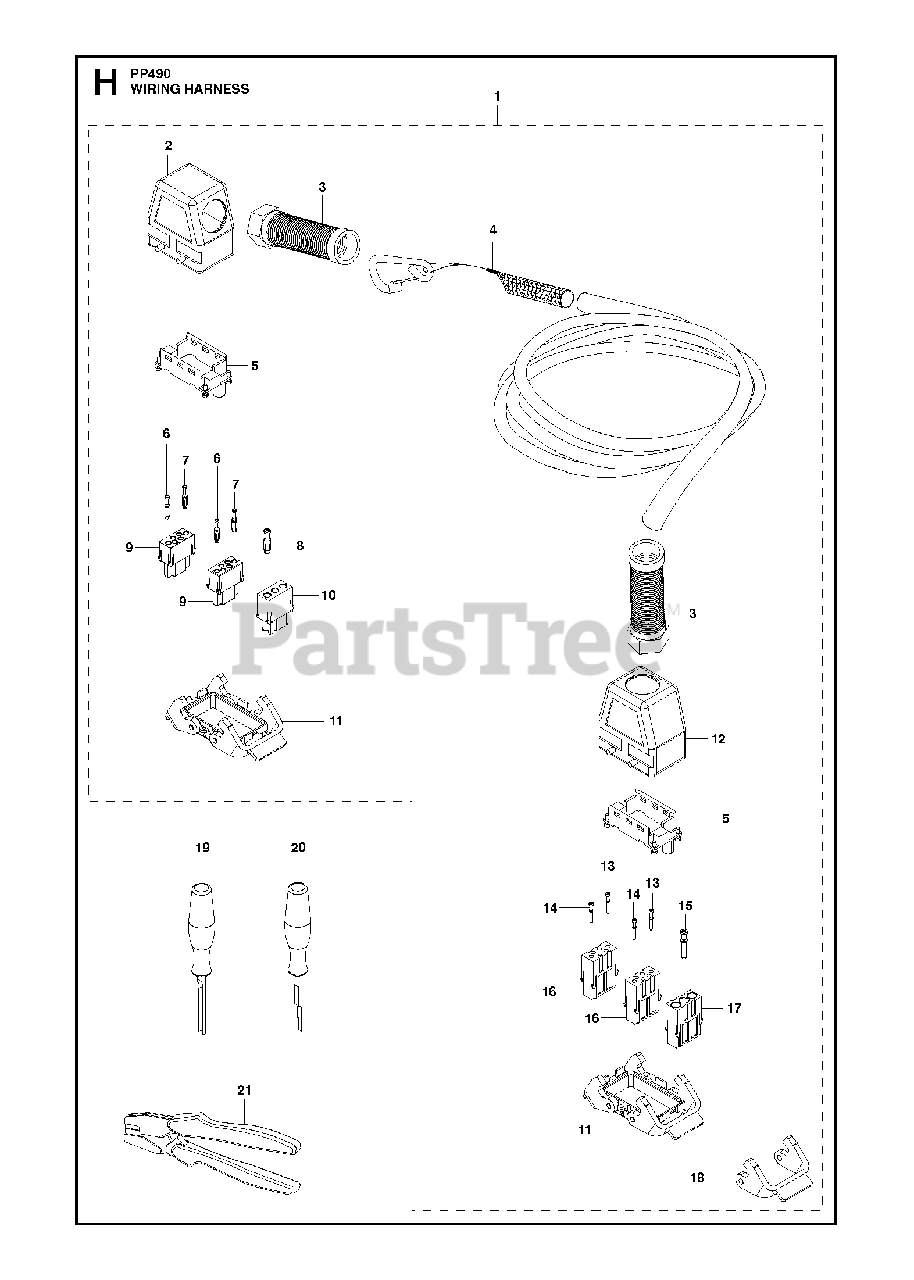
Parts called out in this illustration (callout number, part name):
6	TERMINALFemale 0,75mm²
7	TERMINALFemale 2,5mm²
14	TERMINALMale 0,75mm²
